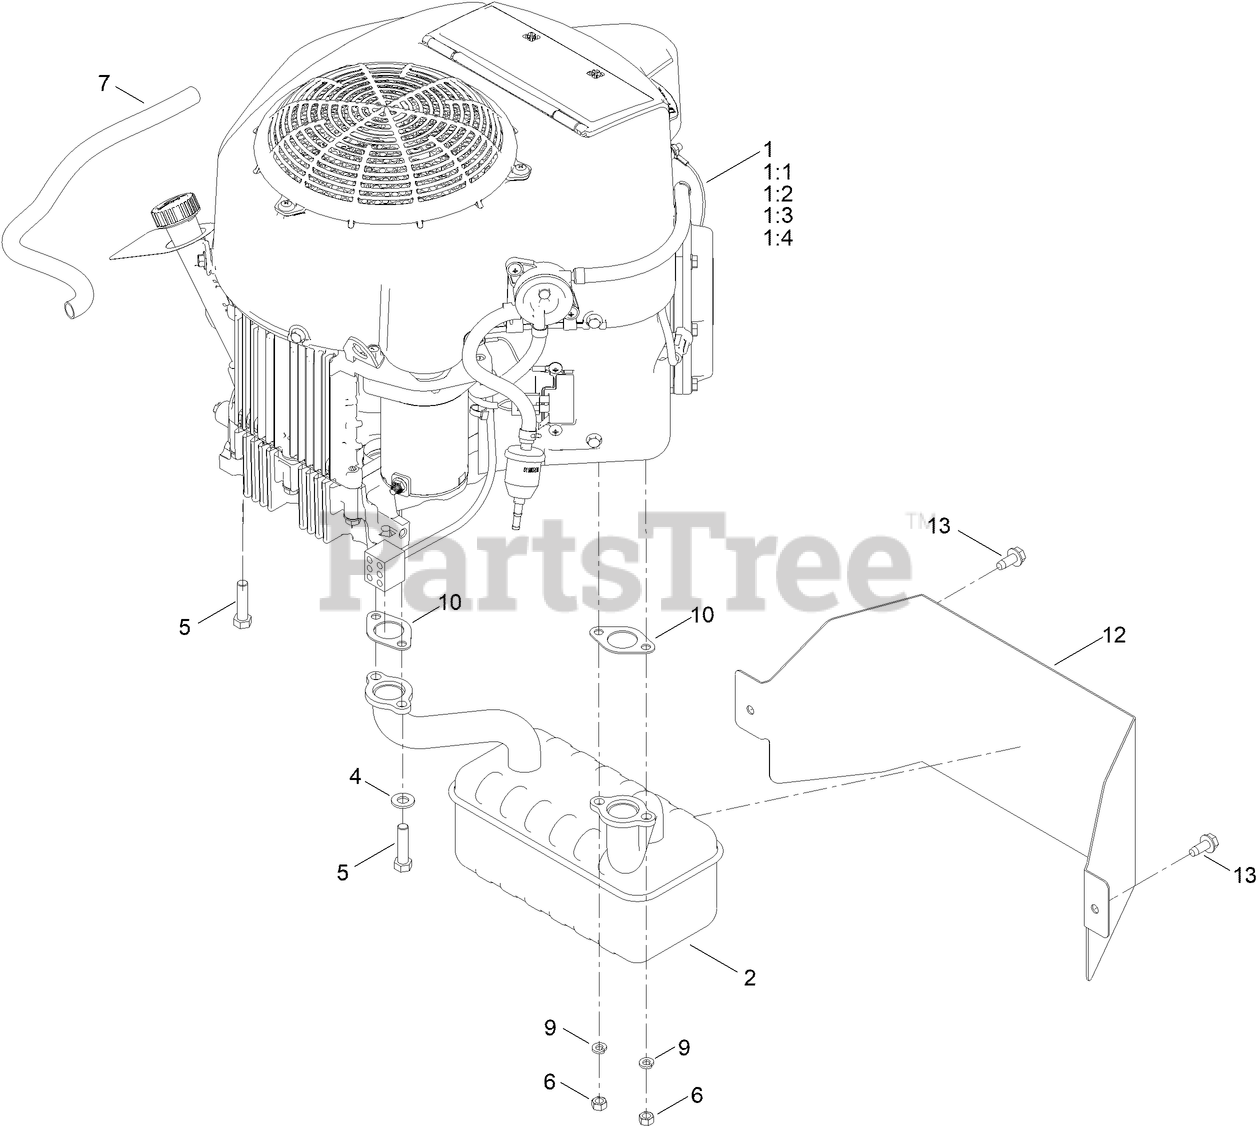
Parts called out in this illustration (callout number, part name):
1:1	FILTER-OIL
1:2	Filter-Fuel
1:3	PLUG-SPARK
1:4	FILTER-AIR, PAPER
2	MUFFLER
4	WASHER-FLAT
5	BOLT-HH
7	TUBE-DRAIN, OIL
9	WASHER-LOCK
10	GASKET-EXHAUST
12	HEAT SHIELD - MUFFLER
13	SCREW-HWHTF
